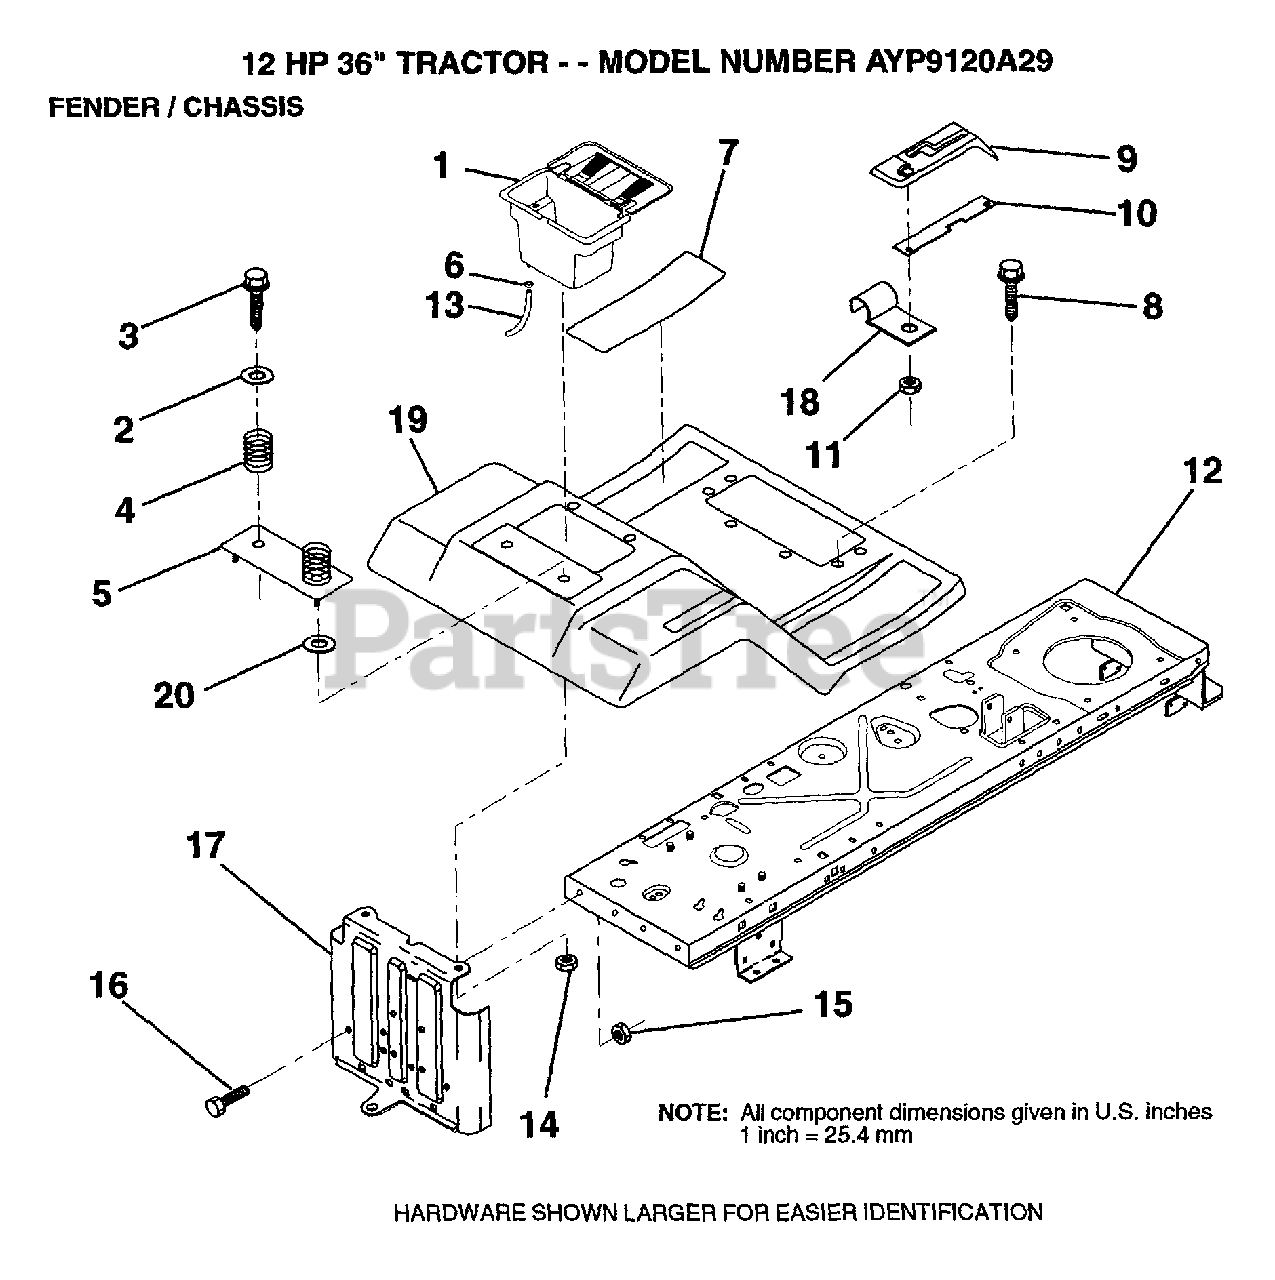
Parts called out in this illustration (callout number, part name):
2	WASHER
3	SCREW
4	SPRING COMPRESSIO
5	BTRY FENDER PLATE
6	HOSE CLAMP T
7	PAD FOOTREST
8	SCREW
9	CONSOLE SHFT 4SP
11	NUT
14	NUT
16	BOLT
17	DRAWBAR
18	"CLIP,INSULATOR"
